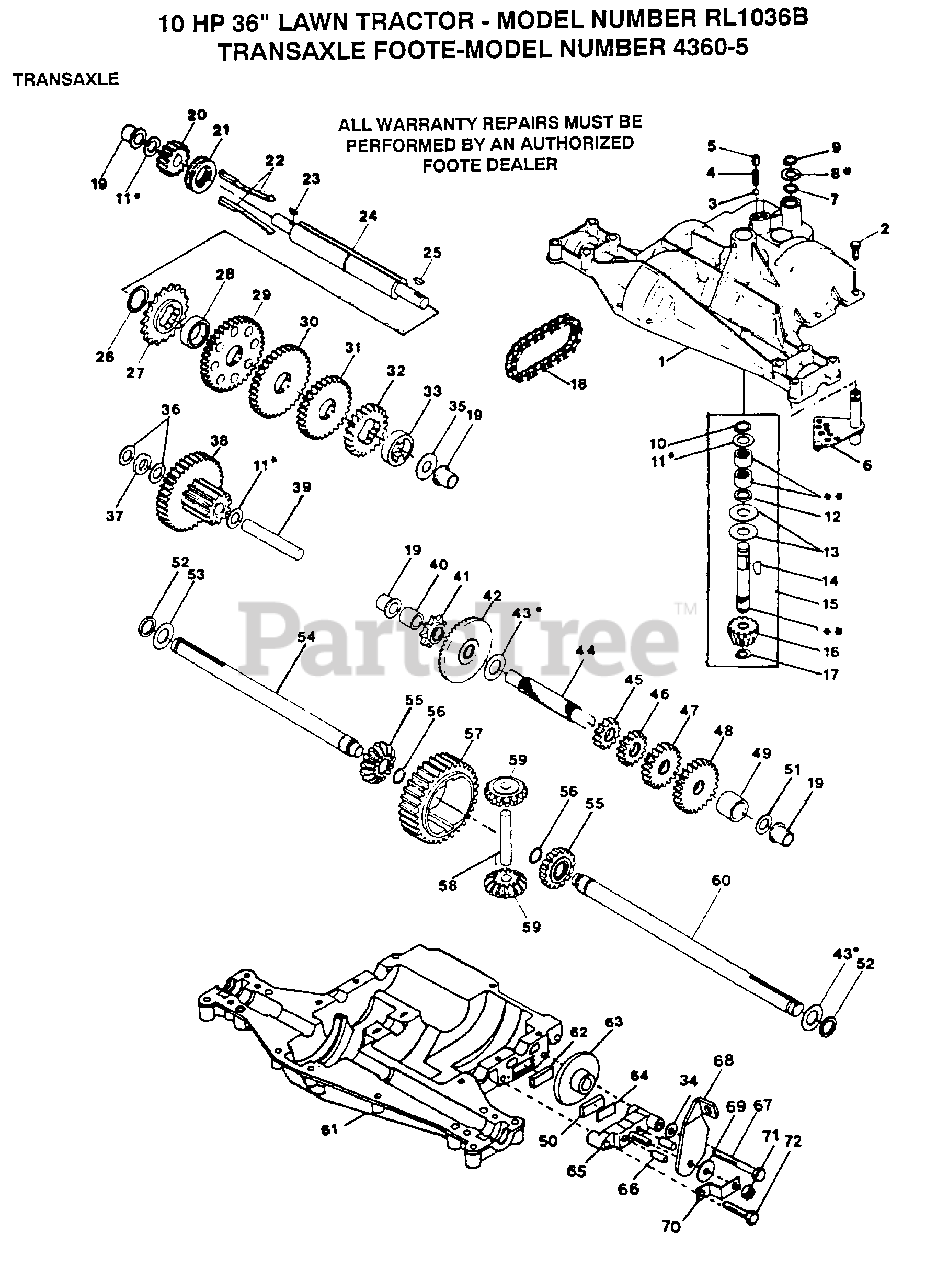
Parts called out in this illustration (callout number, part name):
1	HOUSING UPPER
3	BALL DETENT
4	SPRING, DETENT
5	SCREW, SET
6	ASSY SHIFTER
8	WASHER PLAIN
9	RING RETAINING
10	RING RETAINING
11	WASHER PLAIN
11	WASHER, PLAIN .632 X 1.00 X .026
11	WASHER, PLAIN .632 X 1.00 X .060
13	WASHER, PLAIN .632 X 1.38 X .046
14	KEY WOODRUFF #9
15	ASSY KIT INPUT SHAFT
16	PINION, BEVEL, 14 TEETH
17	RING, RETAINING
18	CHAIN, 24 PITCHES
19	BEARING, FLANGE
20	GEAR SPUR, 14 TEETH
21	COLLAR CLUTCH
22	KEY CLUTCH
23	KEY WOODRUFF #3
24	SHAFT INTERMEDIATE
25	KEY, WOODRUFF, #61
26	RING, RETAINING
27	SPROCKET, 18 TEETH
29	GEAR, SPUR, 37 TEETH
30	GEAR, SPUR, 30 TEETH
31	GEAR, SPUR, 25 TEETH
34	WASHER PLAIN
35	WASHER, PLAIN .640 X 1.37 X .061
36	WASHER, PLAIN .632 X 1.00 X .026
37	SPACER .630 X 1.00 X .169
38	ASSY GEAR COMB 12&35 TEETH
39	SHAFT IDLER
40	SPACER .635 X .875 X .755
41	SPROCKET, 9 TEETH
42	GEAR, BEVEL, 42 TEETH
43	WASHER PLAIN
43	WASHER, PLAIN .758 X 1.25 X .031
44	SHAFT, DRIVE
45	GEAR, SPUR, 12 TEETH
46	GEAR, SPUR, 20 TEETH
47	GEAR, SPUR, 25 TEETH
48	GEAR, SPUR, 31 TEETH
49	SPACER .781 X 1.00 X .750
50	PUCK, FRICTION
51	WASHER, PLAIN .632 X 1.00 X .060
53	WASHER PLAIN
54	AXLE LEFT HAND
55	GEAR, MITER, 15 TEETH
56	RING, RETAINING
57	GEAR, SPUR, 32 TEETH
58	SHAFT, CROSS
59	GEAR, MITER, 15 TEETH
60	AXLE, R.H.
61	HOUSING LOWER
62	PUCK, FRICTION
63	DISC, BRAKE
65	JAW, BRAKE
66	PIN, DOWEL
67	SCREW TAPPING
68	LEVER, ACTUATING
69	WASHER, PLAIN .321 X 1.00 X .055
70	BRACKET, ANTI-ROTATION
71	LOCKNUT 5/16-24
72	SCREW TAPPING
